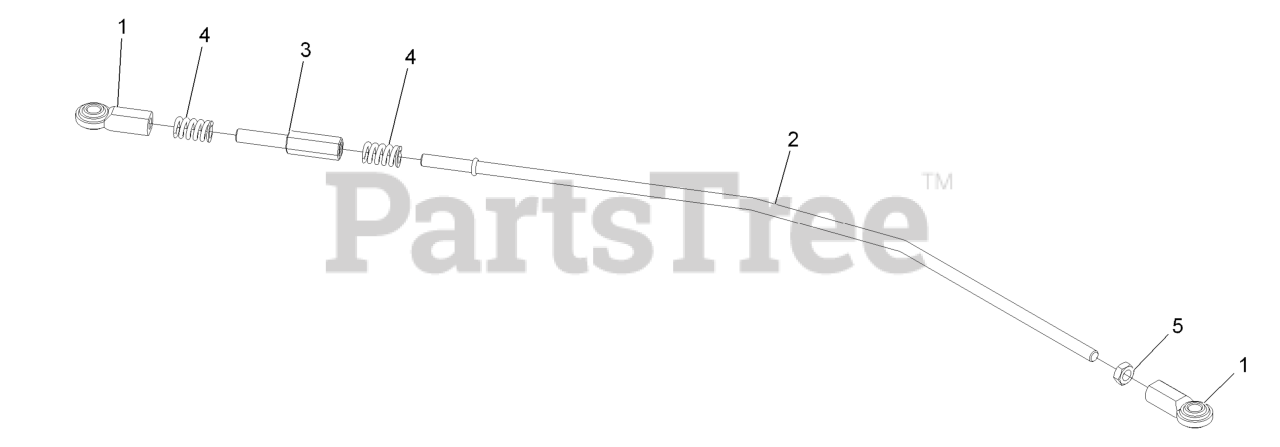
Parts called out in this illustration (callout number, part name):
1	Balljoint
2	Link-Lower,Motion Control
3	Rod-Adjustment
4	Spring-Compression
5	Nut-Jam 3/8-24
